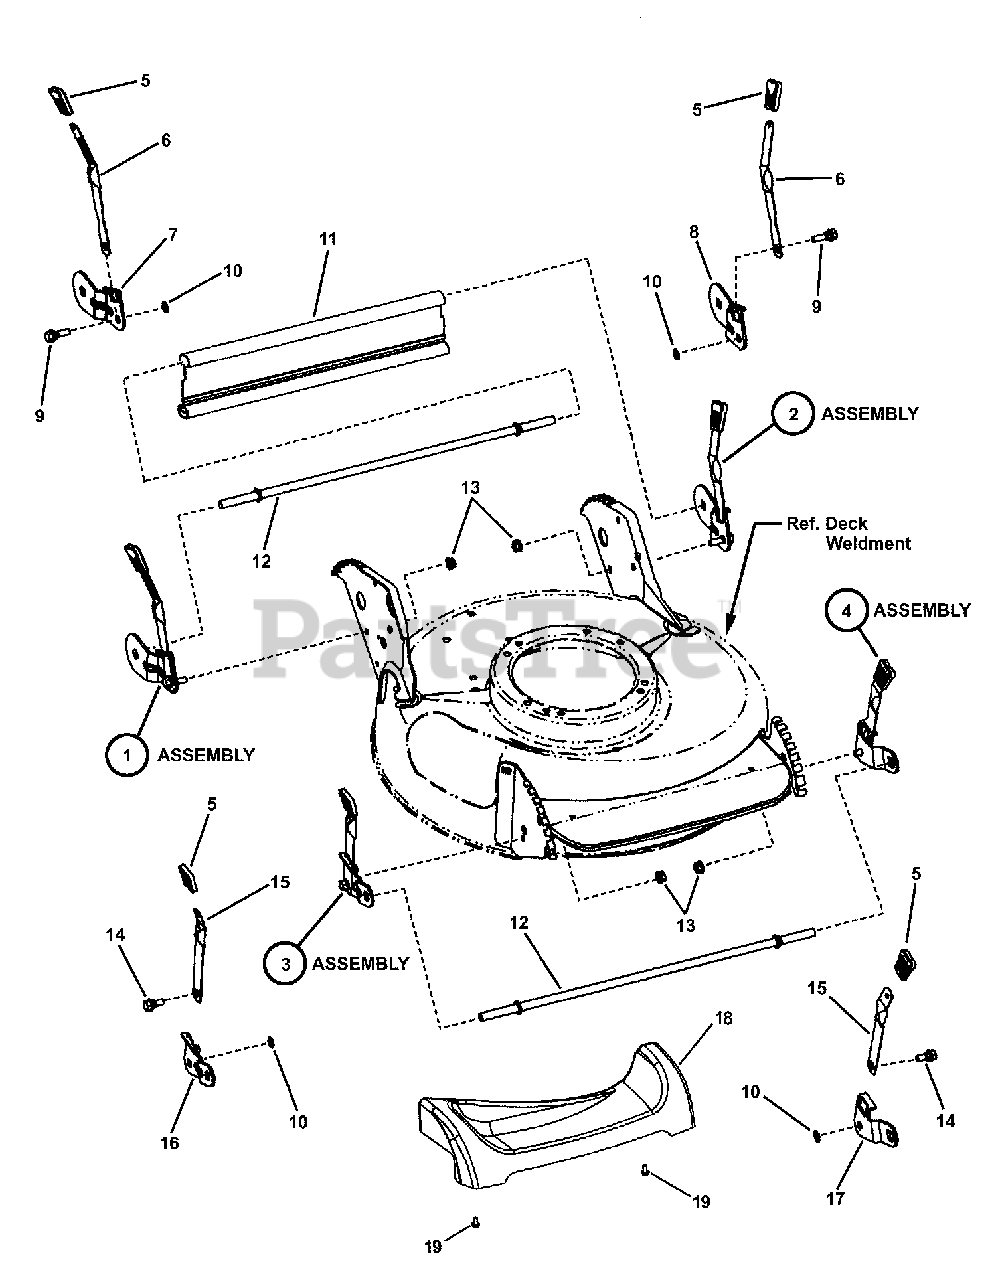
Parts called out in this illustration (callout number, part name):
1	ASSEMBLY, Wheel Arm, Right Rear (Push)
2	ASSEMBLY, Wheel Arm, Left Rear Long (Push)
3	ASSEMBLY, Right Wheel Arm
4	ASSEMBLY, Left Wheel Arm (.512" Square Hole)
5	GRIP, Height Latch - Black (1.3" Wide)
5	GRIP, Height Latch - Black (1.7" Wide)
6	LATCH, Height Adjusting (long)
7	ARM, Wheel, Right Rear
8	ARM, Wheel, Left Rear
9	BOLT, 5/16-18 x 1" Hex Washer Face Shoulder
10	RETAINER, 5/16" Bolt
11	GUARD, Rear (21 Push)
12	AXLE, Front, Easy Line (3/8-16 Threads)
13	NUT, 5/16-18 Hex Flange Lock, GR 5
14	BOLT, 5/16-18 x 3/4" Hex Washer Face Shoulder
15	LATCH, Height
16	WHEEL ARM, R.H. Front (Round Hole)
17	WHEEL ARM, L.H. Front (Square Hole)
18	COVER, Front 21" walk
19	SCREW, Round Washer Head Torx, Hi-Lo
